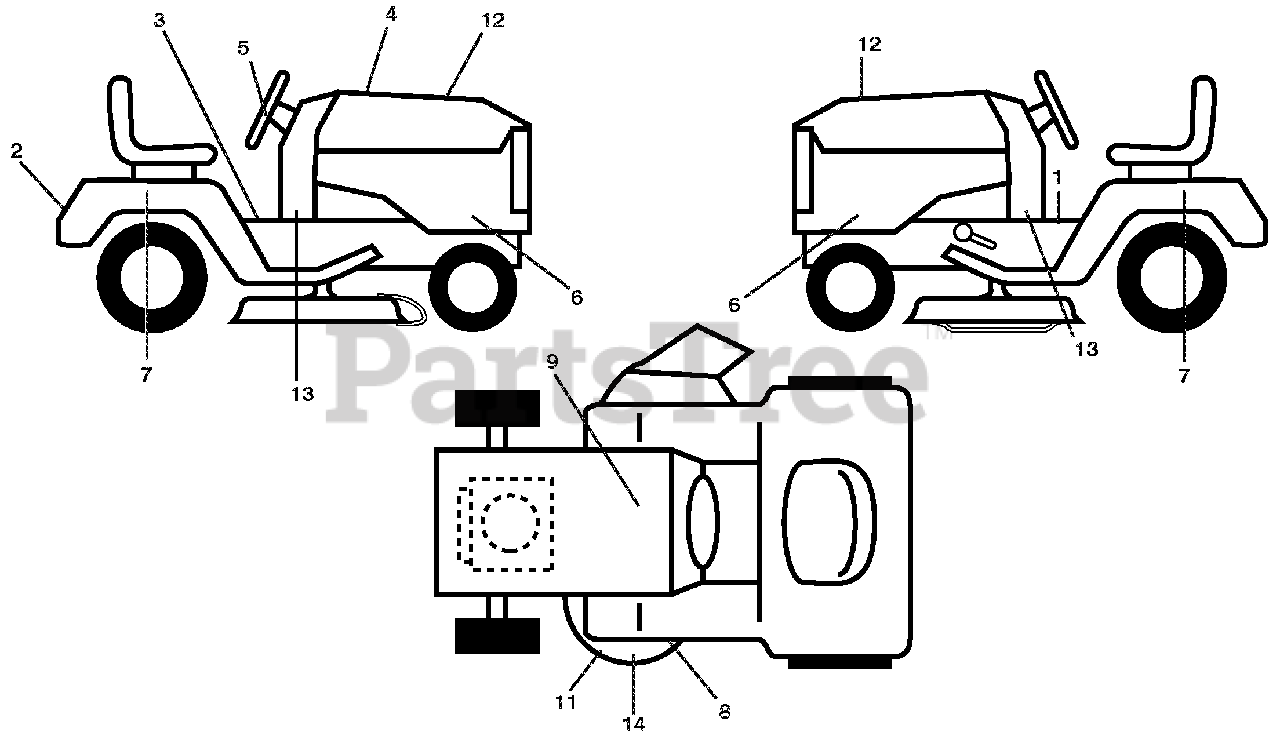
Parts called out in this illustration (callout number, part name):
1	DECAL, WARNING START INST.
2	DECAL.FENDER.REAR.ARIENS
3	DECAL.FENDER
4	DECAL, REPLACEMENT
5	DECAL.WHEEL.STEER.ARIENS
6	DECAL.SDPNL.PWRDBY KOHL.ARIENS
7	DECAL, FENDER
8	DECAL.MOWER.SCH.48/54.PREM.
9	DECAL.BAT.DAN/POI P/L SYM.WPN
11	DECAL.MOWER.CAUTION.TENSION.AR
12	DECAL.HOOD.RH.PRECISION.ARIENS
13	DECAL.DASH.LOWER
14	DECAL.MOWER.WARN.KEEP HAND AWY
